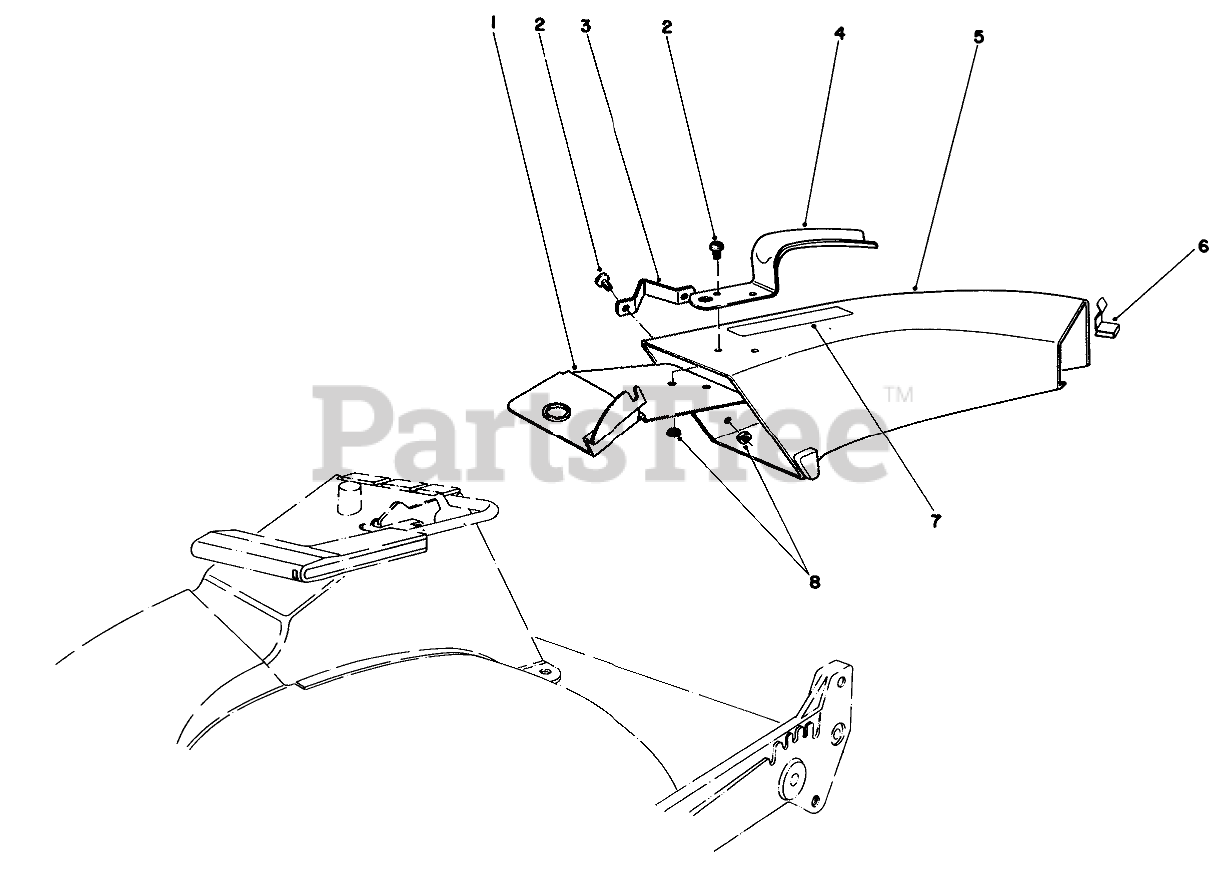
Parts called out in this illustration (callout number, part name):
1	Plate-Discharge Chut
2	10-24 X 5/8 PAN HD MS
3	SIDE BRACKET
4	CHUTE HANDLE
5	Chute Assembly
6	Clip
7	DECAL CAUTION
8	NUT-LOCK, NI
